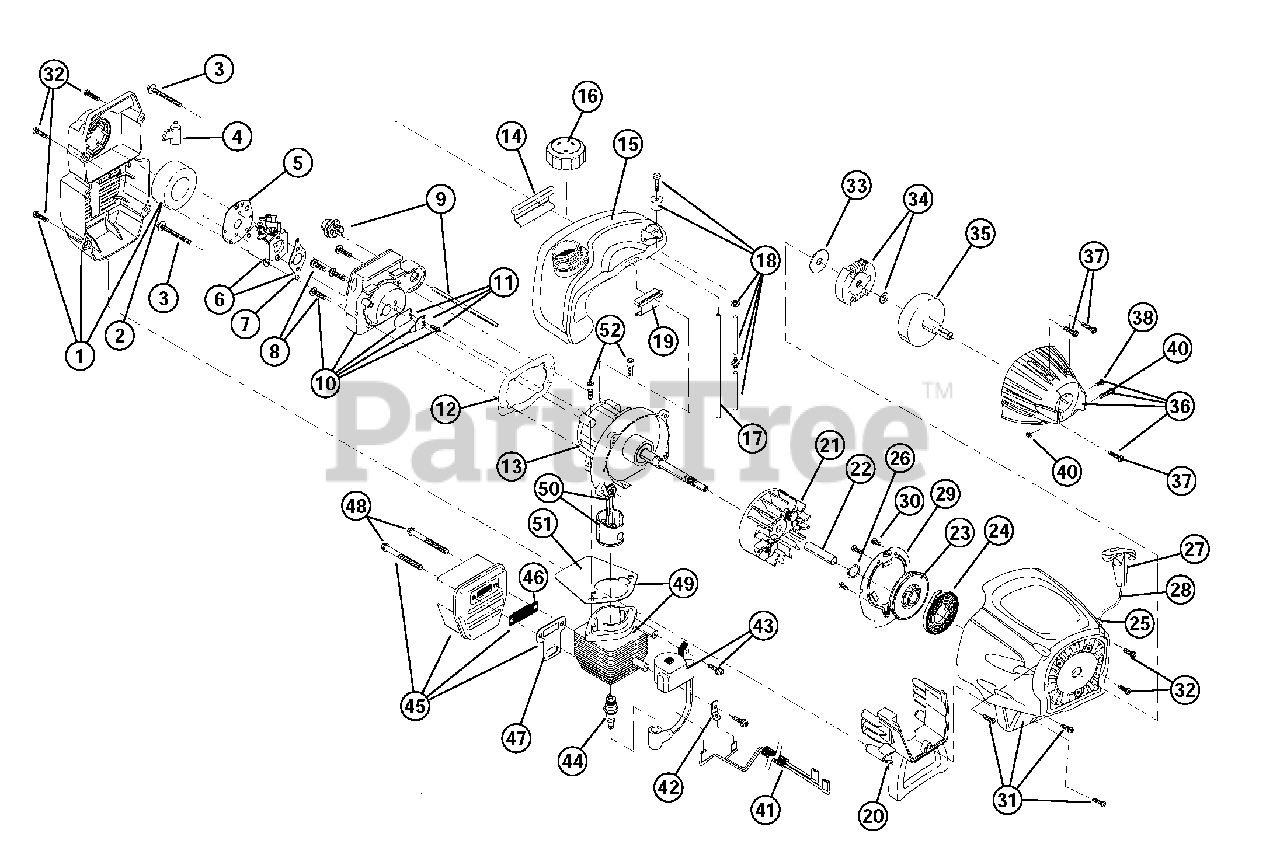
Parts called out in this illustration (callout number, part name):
1	Air Cleaner/Muffler Cover Assembly
2	Air Cleaner Filter
3	Carburetor Mounting Screw
4	Choke Extension
5	Choke Plate
6	Carburetor Assembly
7	Carburetor Gasket
8	Carb Mount Screw
9	Primer and Hose Assembly
10	Carb Mount Assembly
11	Reed Assembly
12	Carburetor Mount Gasket
13	Crank Case Service Assembly
14	Rear Mounting Pad
15	Fuel Tank Assembly
16	Fuel Cap Assembly
17	Fuel Return Line
18	Fuel Line Assembly
19	Front Mounting Pad
20	Shroud Extension and Stand
21	Flywheel Assembly
23	Recoil Pulley Assembly
24	Recoil Spring
25	Rope Guide
26	Pulley Retainer
27	Pull Handle
29	Pressure Plate Assembly
30	Plate Screw
31	Starter Housing Assembly
32	Housing Screw
33	Clutch Washer
34	Clutch Rotor Assembly
35	Clutch Drum Assembly
36	Clutch Cover Assembly
37	Cover Screw
38	Anti-Rotation Screw
39	Clamping Screw
40	Clamping Nut
41	Wire Leads and Sleeve
42	Ground Tab
43	Module Assembly
44	Spark Plug
45	Muffler Assembly
46	Spark Arrestor Screen
47	Exhaust Gasket
48	Muffler Mounting Bolt Assembly
49	Cylinder Assembly
50	Piston and Rod Assembly
51	Cylinder Gasket
52	Cylinder Bolt
